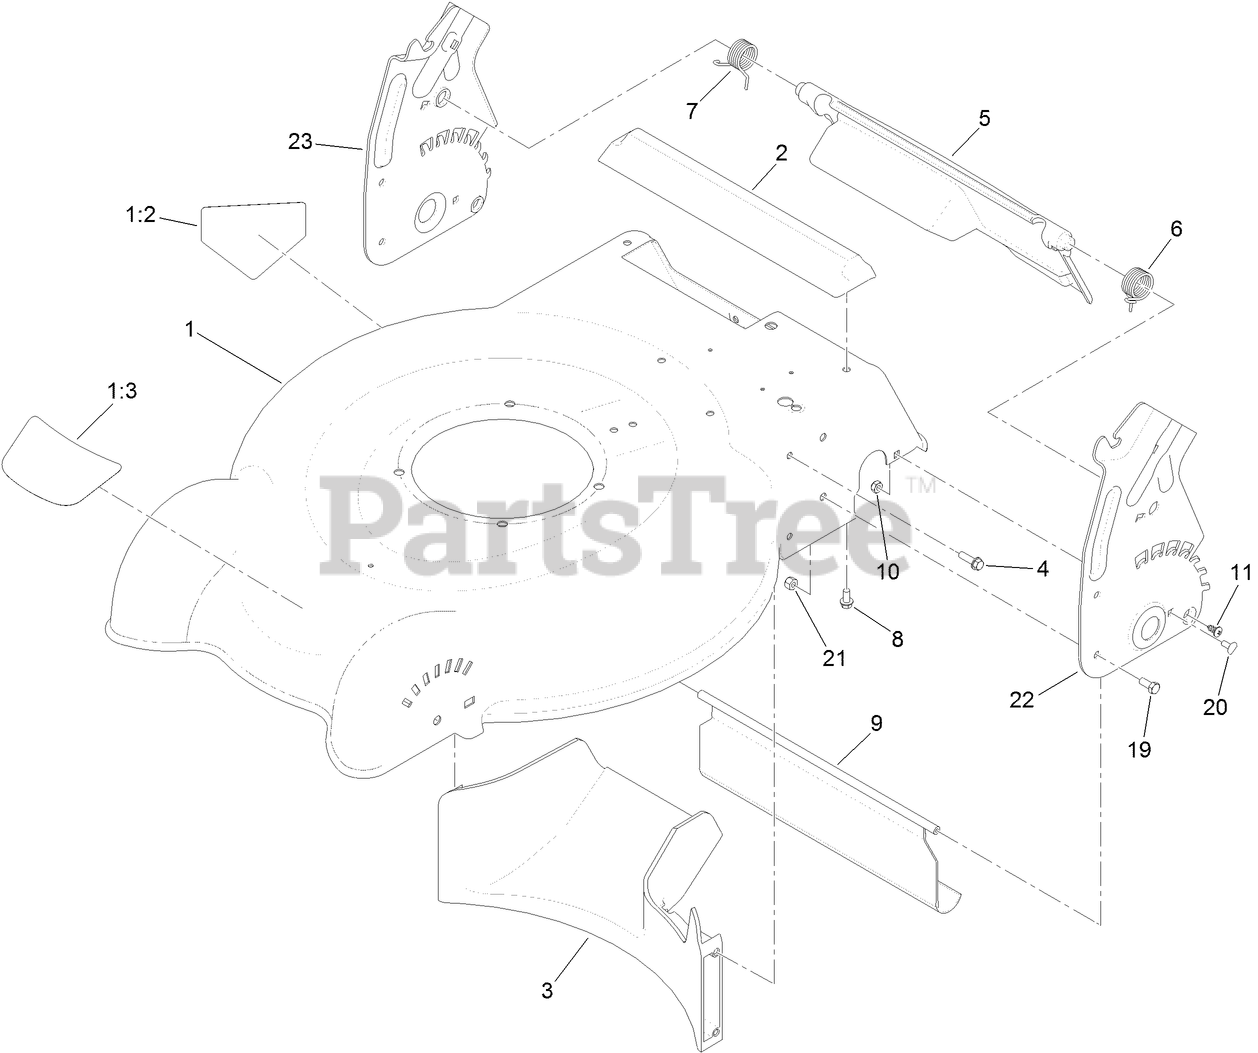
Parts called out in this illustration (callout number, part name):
1	HOUSING ASM
1:2	DECAL-DANGER
1:3	DECAL-DECK
2	CHUTE-REAR
3	BAFFLE-REAR
4	SCREW-HWH
5	REAR DEFLECTOR ASM
6	SPRING-TORSION, LH
7	SPRING-TORSION, RH
8	SCREW-PLASTITE
10	NUT-LOCK, NI
11	SCREW-PTH
19	SCREW-HH
20	SCREW-CARR
21	NUT-LOCK, NI
22	PLATE-HOC, LH
23	PLATE-HOC, RH
